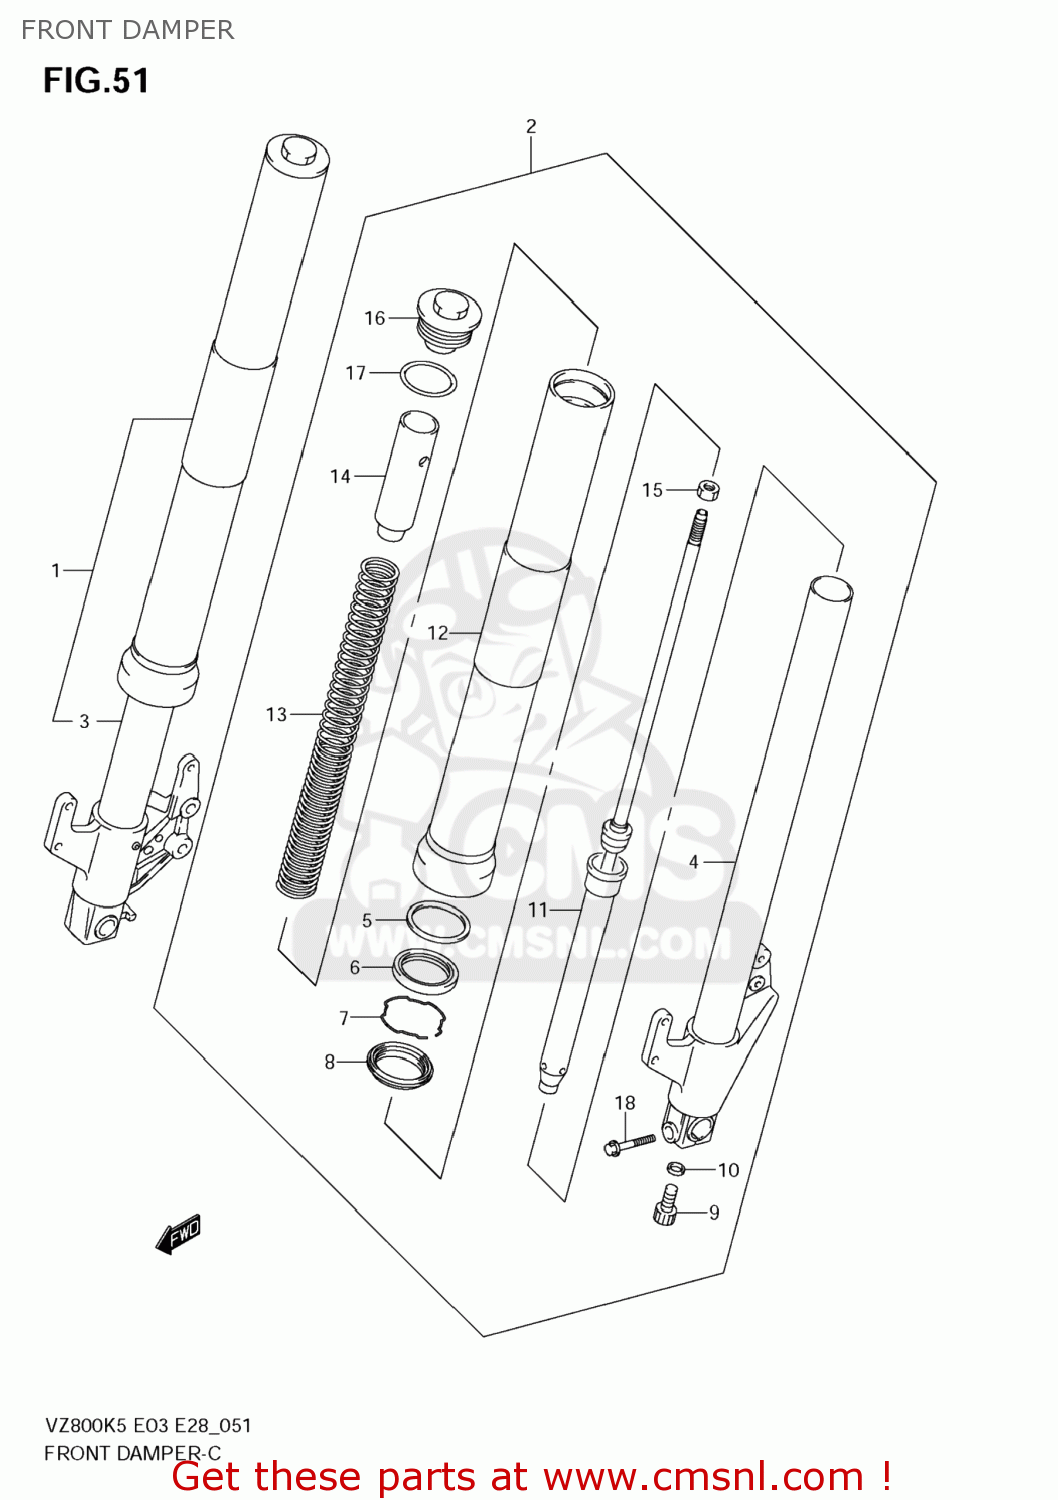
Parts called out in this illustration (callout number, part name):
1	DAMPER ASSY,FR FORK,R
2	DAMPER ASSY,FR FORK,L
3	TUBE,INNER,R
4	TUBE,INNER,L
5	WASHER,FORK OIL SEAL
6	SEAL,OIL
7	RING,OIL SEAL STOPPER
8	SEAL,DUST
9	BOLT,CYLINDER
10	GASKET,CYLINDER (NAS)
11	CYLINDER
12	TUBE,OUTER
13	SPRING,FR
14	SPACER,SPRING
15	NUT,ROD
16	CAP
17	O RING
18	BOLT
